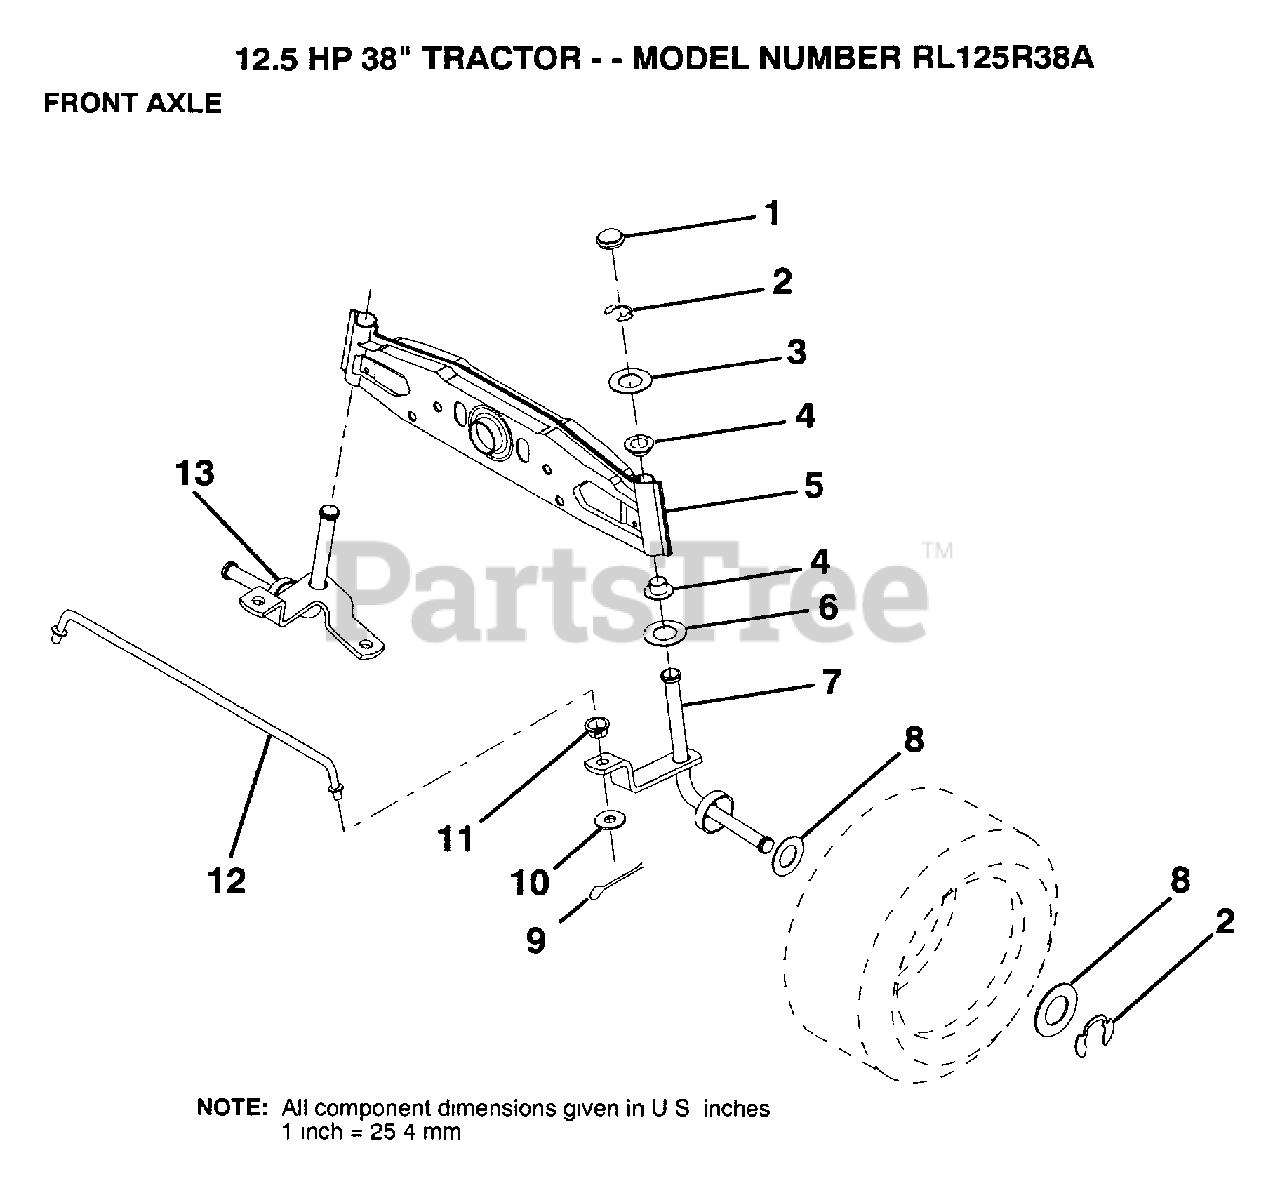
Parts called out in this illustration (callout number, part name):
1	CAP
2	RING
3	WASHER
4	NYLINER
5	AXLE FRONT
6	WASHER .T
7	SPINDLE RH
8	WASHER
9	COTTER PIN
10	WASHER
11	BUSHING.DRAGLINK
12	ROD TIE
13	SPINDLE LH
